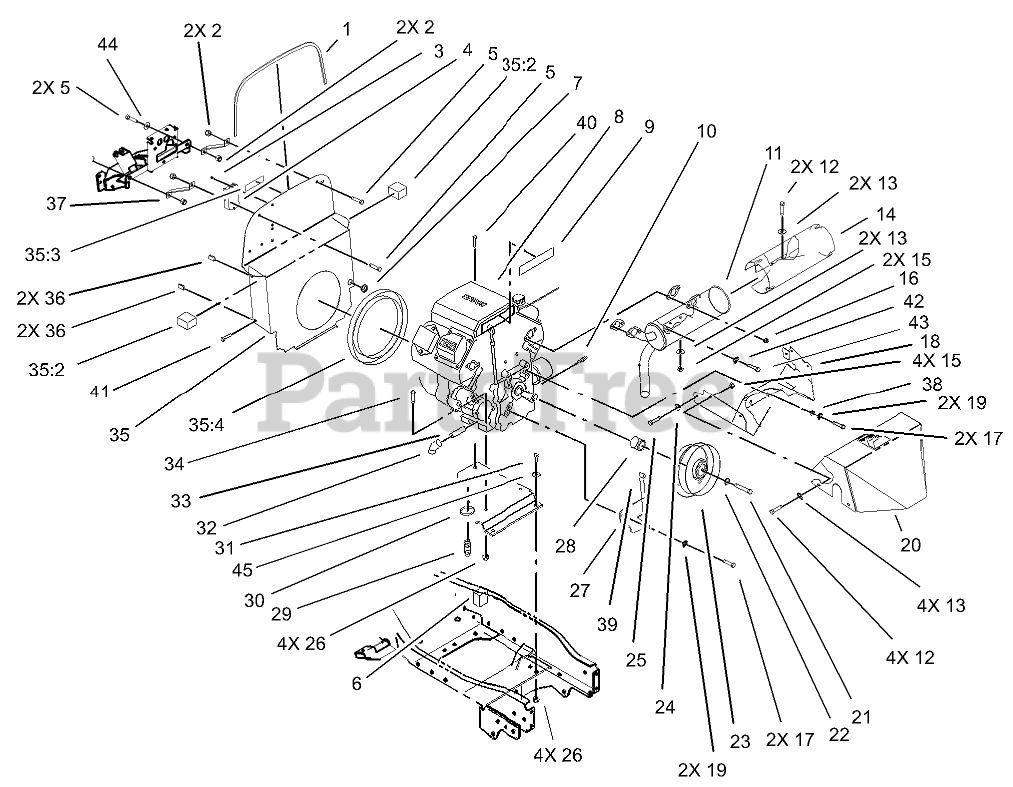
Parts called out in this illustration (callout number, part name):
1	TRIM-LOCK
2	NUT-LOCK, NI
3	SCREW-HWH
4	MODULE-LOW VOLTAGE
5	SCREW-HH
6	SEAL-FOAM, SIDE
7	GROMMET
9	DECAL - 20 HP ENGINE
10	SENDER-OIL TEMPERATURE
11	MUFFLER
12	SCREW-HH
13	WASHER-FLAT
14	REFLECTOR - HEAT
15	NUT-LOCK, CONE
16	NUT-HF
17	SCREW-HH
18	SHROUD-MUFFLER
19	WASHER-LOCK
20	SHROUD-MUFFLER
21	SCREW-HH
22	WASHER-FLAT
23	CLUTCH-PTO
24	WASHER-LOCK
25	SCREW-HH
26	NUT-LOCK, NI
27	CLUTCH-STOP
28	SPACER-CLUTCH
29	VALVE-DRAIN, OIL
30	PLATE-ENGINE
31	SCREW-HH
32	ELBOW-90 DEGEE
33	NIPPLE
34	SCREW-HH
35	ASM - BULKHEAD W/DECAL
35:2	SEAL-FOAM, SIDE
35:3	DECAL - WARNING
35:4	SEAL-FOAM
37	BRACKET-BULKHEAD
38	WASHER-FLAT
39	BUMPER
40	SCREW-TAPTITE
41	SCREW-HH
42	WASHER-LOCK
43	SCREW-HHF
44	WASHER-PLAIN
45	WASHER-FLAT
